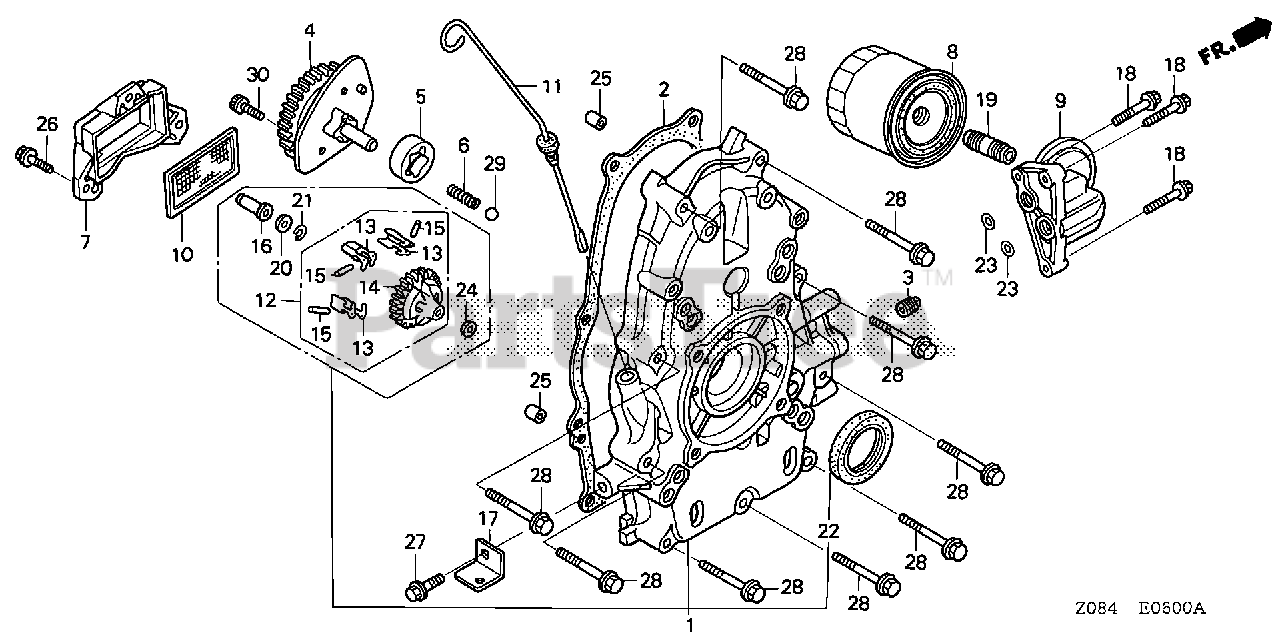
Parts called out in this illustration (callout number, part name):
1	COVER ASSY., CRANKCASE
2	GASKET, CASE COVER
3	BOLT, SEALING
4	COVER ASSY., OIL PUMP (THREE BOLTS)
5	ROTOR, OIL PUMP (OUTER)
6	SPRING, RELIEF VALVE
7	COVER, OIL FILTER
8	FILTER, OIL (FILTECH TOYO ROKI) (SOLD INDIVIDUALLY)
8	FILTER, OIL (SOLD INDIVIDUALLY)
8	FILTER, OIL (TOYO ROKI) (SOLD INDIVIDUALLY)
9	BASE, OIL FILTER
10	SCREEN, OIL FILTER
11	DIPSTICK, OIL
12	GOVERNOR ASSY.
13	WEIGHT, GOVERNOR
14	HOLDER, GOVERNOR WEIGHT
15	PIN, GOVERNOR WEIGHT
16	SLIDER, GOVERNOR
17	BRACKET, WIRE HARNESS CLIP (B)
18	BOLT, FLANGE (6X28) (CT200)
19	HOLDER, OIL FILTER
20	WASHER (6X16)
21	CLIP, GOVERNOR HOLDER
22	OIL SEAL (38X58X9)
23	O-RING (11.8X2.4)
24	WASHER, PLAIN (6MM)
25	PIN, DOWEL (8X14)
26	BOLT, FLANGE (6X20)
27	BOLT, FLANGE (8X16)
28	BOLT, FLANGE (8X50)
29	BALL, STEEL (#12) (3/8)
30	BOLT, SOCKET (6X16)
